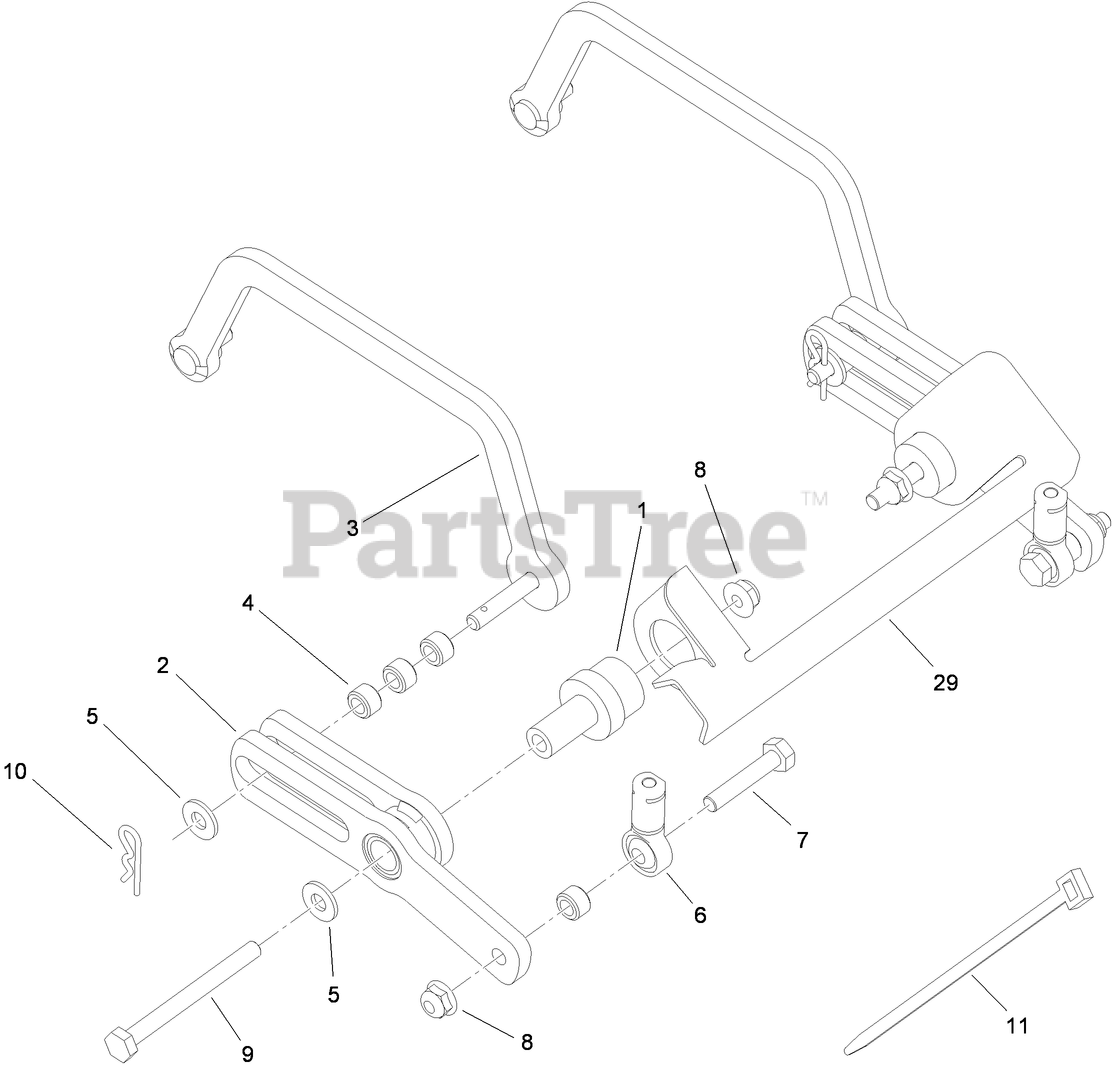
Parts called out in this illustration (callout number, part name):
1	HUB-SHOULDER
2	CONTROL FORK ASM
3	SPEED CONRTOL LINKAGE ASM
4	BUSHING-ROLLER
5	WASHER-FLAT
6	ROD END-BALL JOINT
7	SCREW-HH
8	NUT-HF
9	SCREW-HH
10	PIN-COTTER
11	TIE-CABLE
29	LEVER-SWITCH
